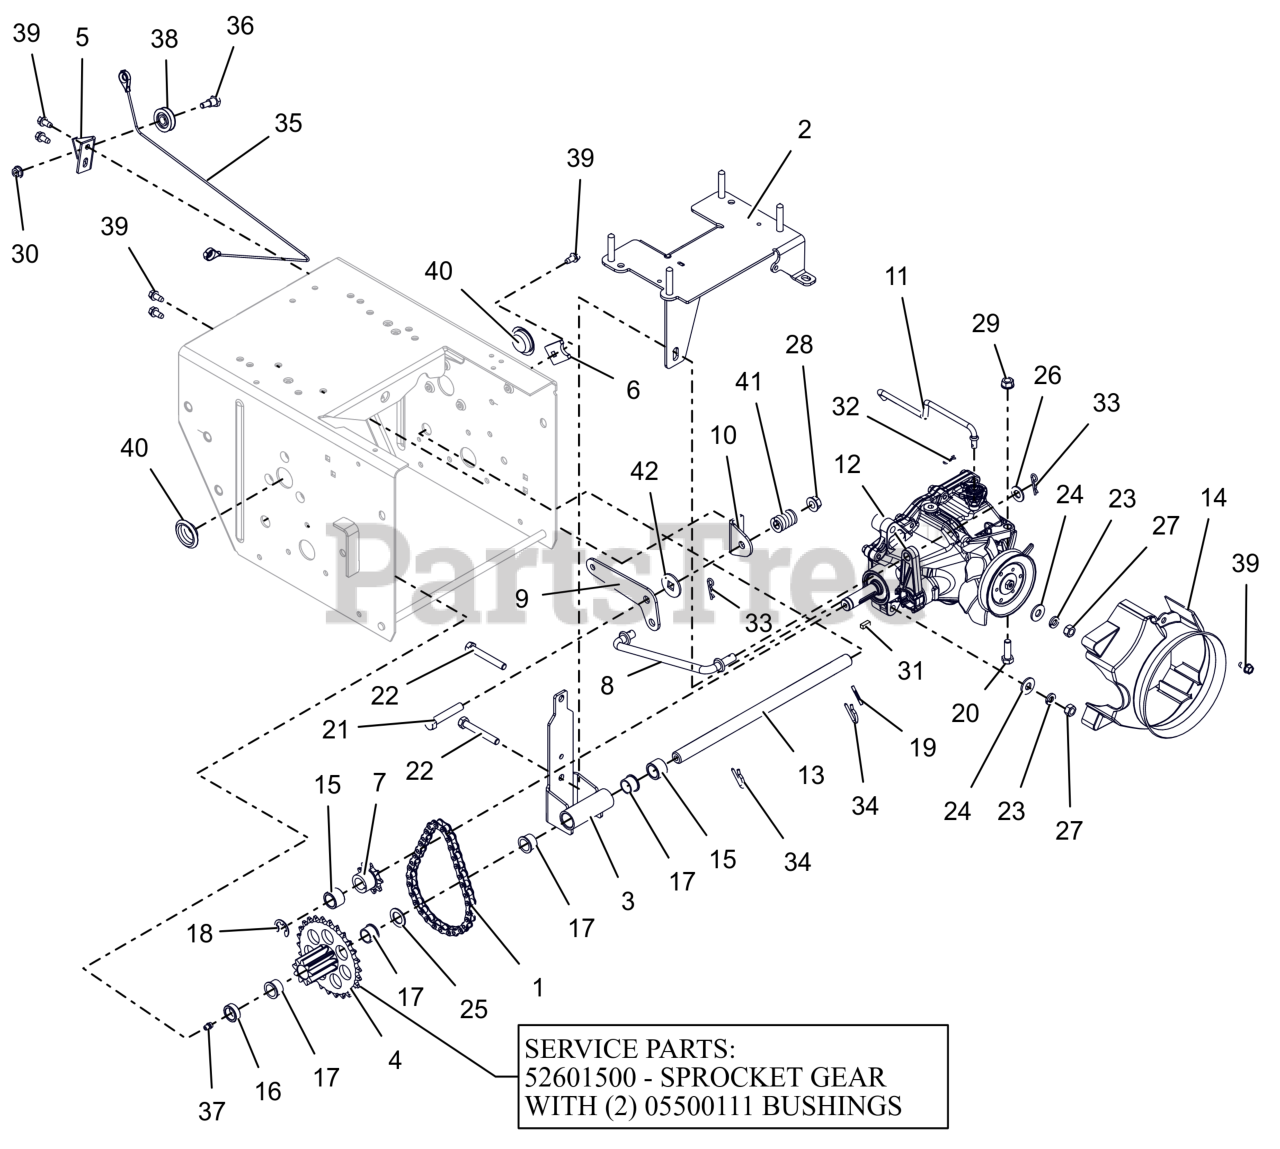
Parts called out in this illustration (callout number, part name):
1	CHAIN - #41, 32 PITCHES
1	PINION & SPROCKET W/BUSHINGS
2	BRACKET, HYDROSTATIC TRANS XLG
3	TRANS MOUNT, TENSIONING, WHEEL
4	PINION & SPROCKET
5	BRACKET, CABLE PULLEY
6	TAB, ANTI ROTATION
7	SPROCKET, PINION 9T W/KEY
8	ROD, HYDRO TRANS SHIFT
9	PIVOT, HYDRO TRANS SHIFT
10	BRACKET, HYDRO SHIFT PIVOT
11	ROD, HYDRO BYPASS
12	TRANSMISSION, HYDROSTATIC
13	SHAFT, PINION - HARDENED
14	SHROUD, HYDROGEAR RT-310
15	SPACER, .635X.880X.611
16	BSHG-SLV, .635X.880X.305
17	BSHG-FLG .625X.750X.500X.875
18	RG-RTNG-EXT .625X.042
19	@PIN-GRV .125X1.00 TP E ALLOY
20	BLT,HEX .31-18X1.00 G5 ZCC
21	BLT,HEX .38-16X2.00 G5 ZCC
22	BLT, HEX .31-18X2.25 G5 ZCC
23	WSHR, LK-HVY .312X.097 ZCC
24	WSHR,FLT .375X.875X.083 ZCC
25	WSHR, FLT .630X1.005X.062 ZCC
26	WSHR,FLT .406X.812X.065 ZCC
27	NUT, HEX .312-18 ZCC
28	NUT-LK-TOP-FLG .38-16 ZC120
29	NUT-LK-TOP-FLG .312-18 GF ZCC
30	NUT-LK-TOP-FLG .250-20 GF ZCC
31	KEY-SQ .187 X .50 X .187
32	PIN, HAIR #178 .06X.77 ZCC
33	PIN, HAIR #213 .08X1.19 ZCC
34	PIN, SPRING CLIP
35	CABLE, TRACTION, HYDRO PRO
36	BOLT, SHLDR -.375 X .375 X .25-20
37	ZERK,FITTING .25X.125 DRIVE IN
38	PULLEY, CABLE
39	SCR-TAP .25-20X.50 HWH ZCC
40	PLUG, HOLE - 1.125"
41	SG-COMP .187X.56X1.62
42	FRICTION WASHER
